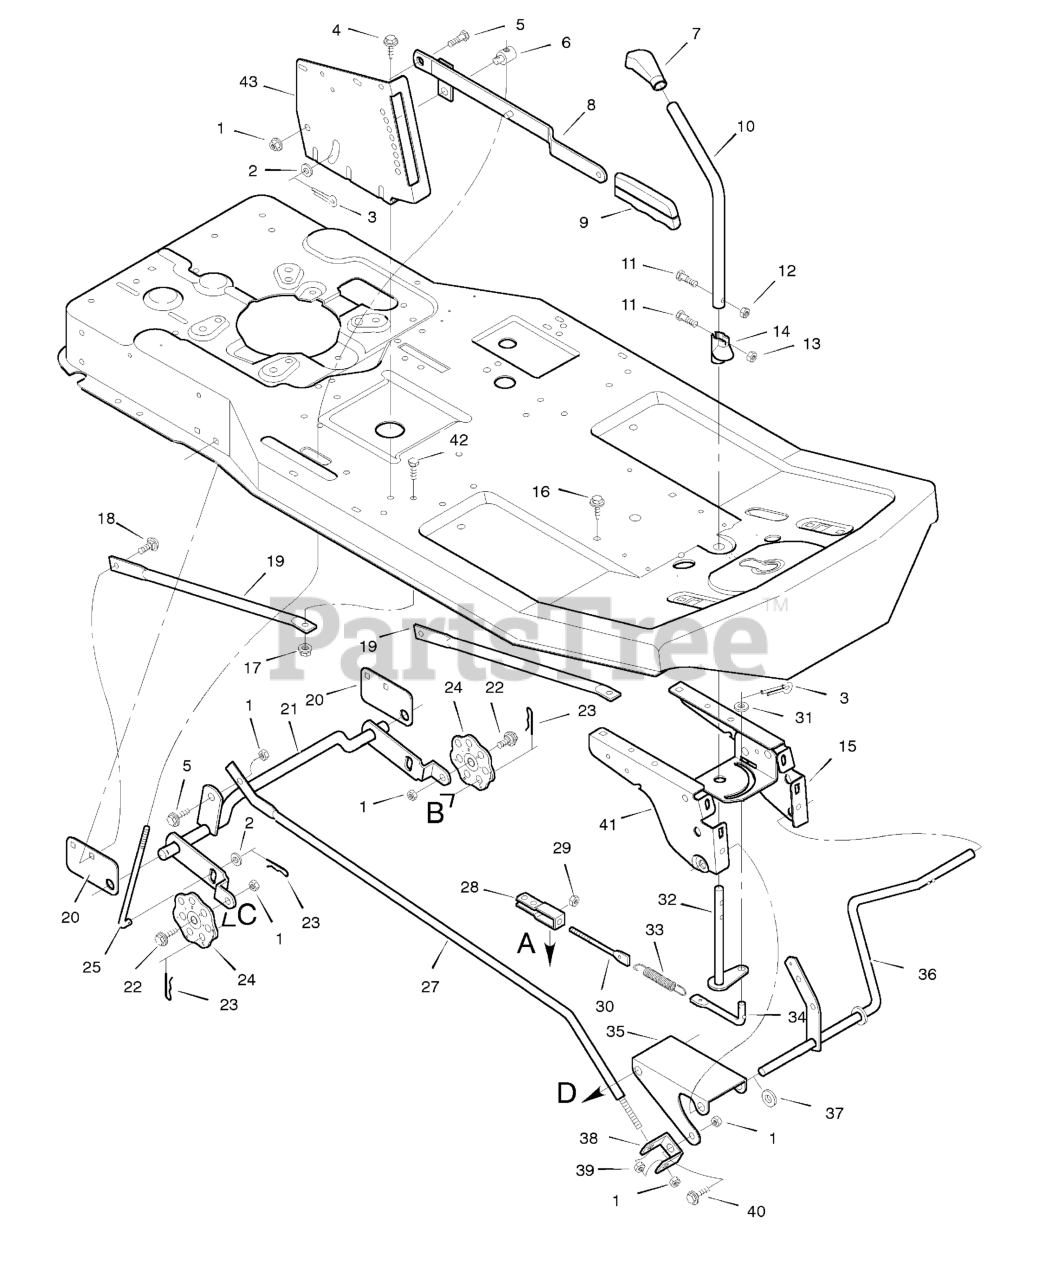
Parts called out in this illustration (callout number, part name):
1	Locknut, Flange
3	Pin, Cotter
5	Bolt, Shoulder
6	Nut, Adjusting
7	Grip, Blade Control
8	Lever Assembly, Lift
9	Grip, Lift Lever
10	Attachment, Clutch
11	Bolt, Hex
12	Locknut
13	Locknut, Flange
14	Cam, Blade Control
15	Plate, Left Suspension
17	Locknut, Flange
18	Bolt, Carriage
19	Strut, Frame
20	Plate, Mounting
21	Rod Assembly, Rear Suspension
22	Bolt, Shoulder
23	Pin, Hair
24	Plate, Adjusting
25	Rod, Lifter
27	Rod, Suspension
29	Nut, Hex
30	Link, Blade Drive
32	Rod and Arm Assembly
33	Spring, Extension
34	Link, Front Deck
35	Bracket, Front Suspension
36	Lever, Pedal
38	Clevis
39	Locknut, Hex
40	Bolt, Shoulder
41	Plate, Right Suspension
42	Bolt, Hex
43	Plate, Index
